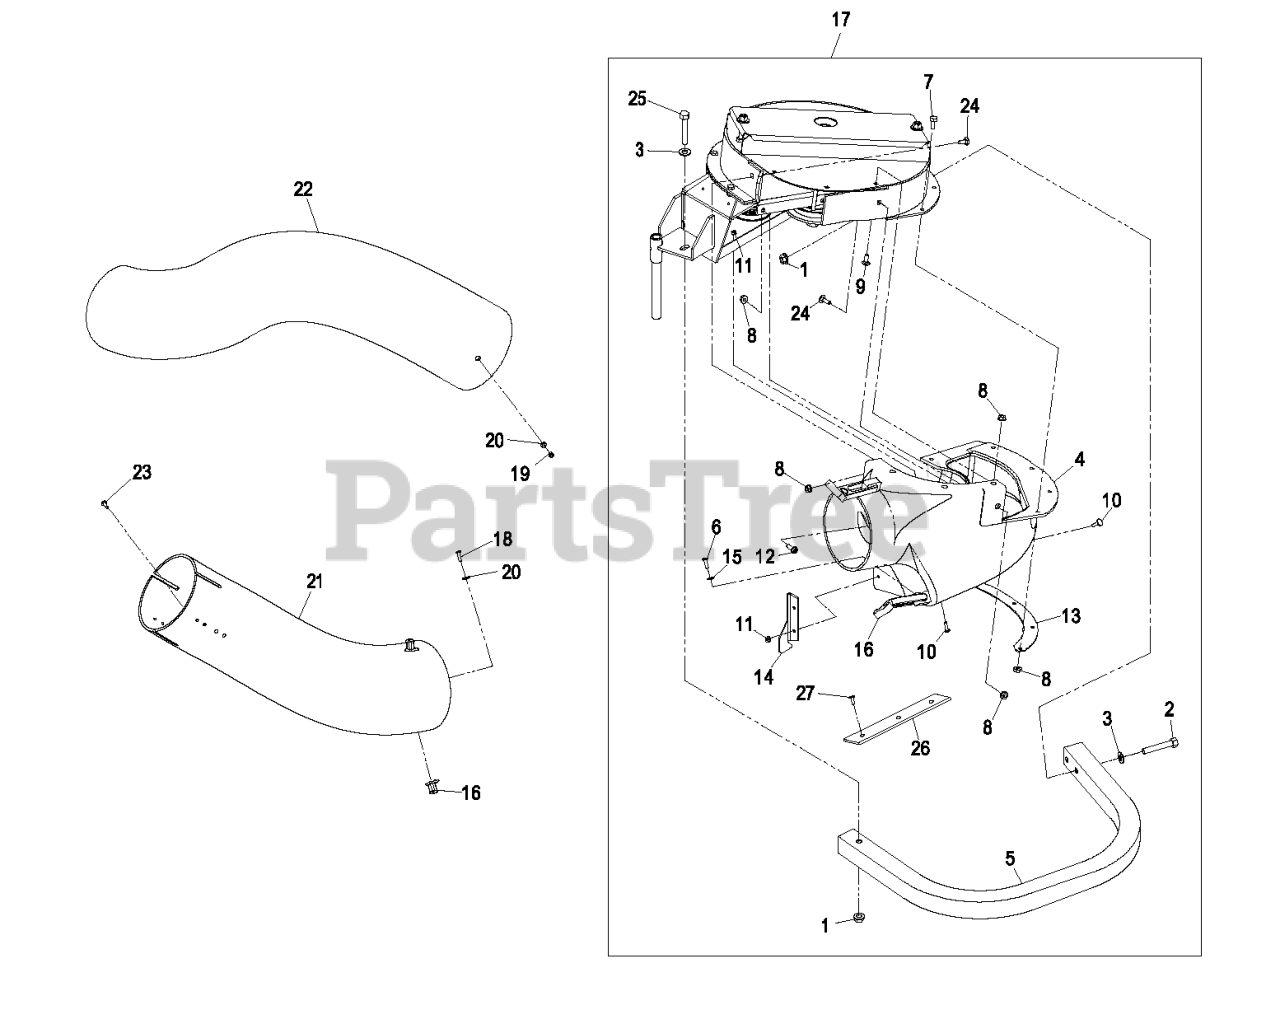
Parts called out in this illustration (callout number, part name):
1	NUT-HHF, WHIZ
2	SCREW-HH
3	WASHER-FLAT
4	ASM,BLOWER CHUTE LHP
6	SCREW-PPH
7	SCREW-HH
9	SCREW-CARR
10	SCREW-HEAD, TRUSS
13	PLATE-BACKING, BLOWER
14	PLATE, FILLER
15	WASHER-FLAT
16	LATCH DRAW
17	ASM,BLOWER
18	SCREW-PPH
19	NUT-LOCK, NI
20	WASHER-FLAT
21	KIT,LOWER TUBE
22	TUBE-UPPER
23	SCREW-HWH
24	BOLT-CARR
25	SCREW-HH
26	PLATE-REINFORCEMENT
27	RIVET-BLIND
